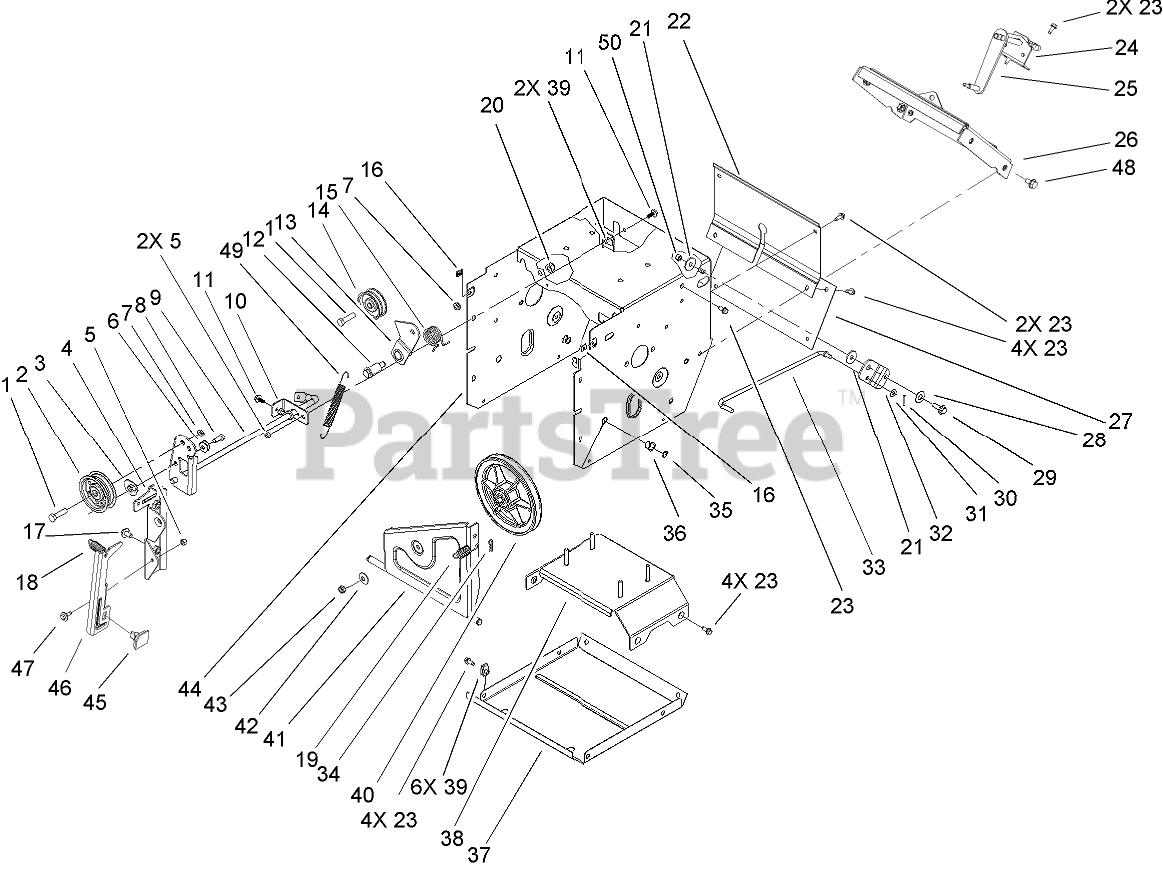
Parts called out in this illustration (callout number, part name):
1	SCREW-HH
2	PULLEY-IDLER
4	BRACKET-IDLER, IMPELLER
5	NUT-LOCK, NI
6	WASHER-BELLEVILLE
7	NUT-LOCK, NI
8	SCREW-HH
9	IMPELLER CLUTCH ASM
10	BRACKET-REAR, CLUTCH
11	SCREW-HHF
12	BOLT-SHOULDER
13	ARM-IDLER, TRACTION
14	PULLEY-IDLER
15	SPRING-TORSION
16	NUT-SPEED, U-TYPE
17	SCREW-HHF
18	SPRING-EXTENSION
19	SPRING-EXTENSION
20	NUT-LOCK, NI
21	WASHER-PIVOT
22	COVER-UPPER
23	SCREW-HWH
24	BRACKET-ROD, SHIFT
25	LEVER-CONTROL, TRACTION
26	SHIFT PLATE ASM
27	COVER-LOWER
28	WASHER
29	SCREW-SHOULDER
30	PIN-COTTER
31	WASHER-PLAIN
32	BELLCRANK-DRIVE
33	LINK-CONTROL, SPEED
34	PIN-COTTER
35	RING-RETAINING
36	BUSHING-NYLINER
37	PAN-BOTTOM
38	BRACE FRAME ASM
40	PULLEY-TRACTION
41	PULLEY PIVOT ASM
42	WASHER-BELLEVILLE
43	NUT-HEX
44	TRACTION FRAME ASM
45	PAD-BRAKE
46	ARM-BRAKE
47	SCREW-SHOULDER
48	SCREW-HWHTF
49	SPRING-EXTENSION
50	NUT-LOCK, NI
